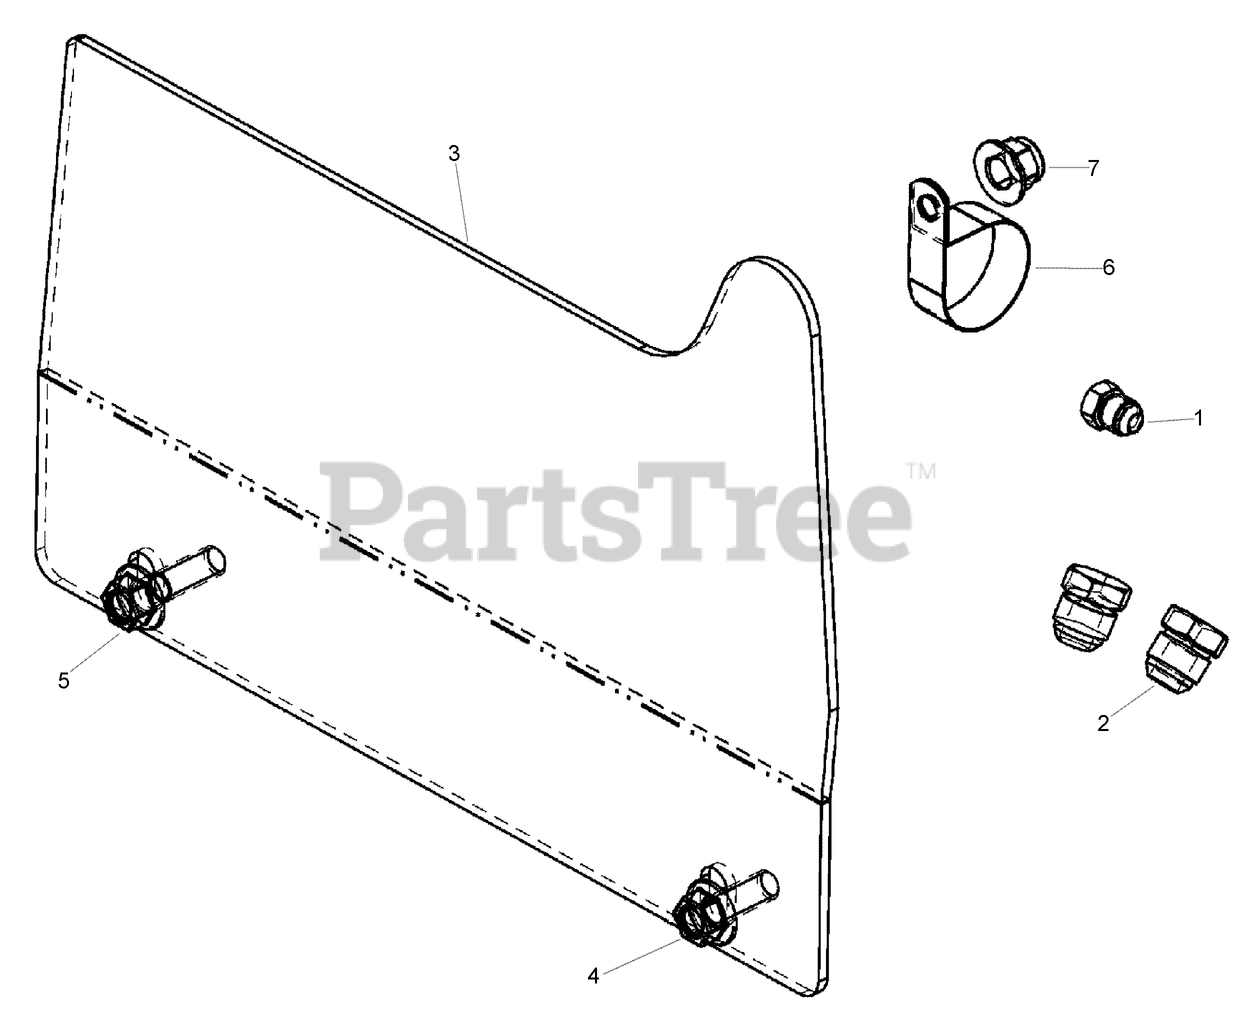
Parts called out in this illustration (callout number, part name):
3	PLATE - Cover
4	SCREW, METRIC FLANGE w/BODY-M12 x 30
7	NUT-HHF, LOCK
